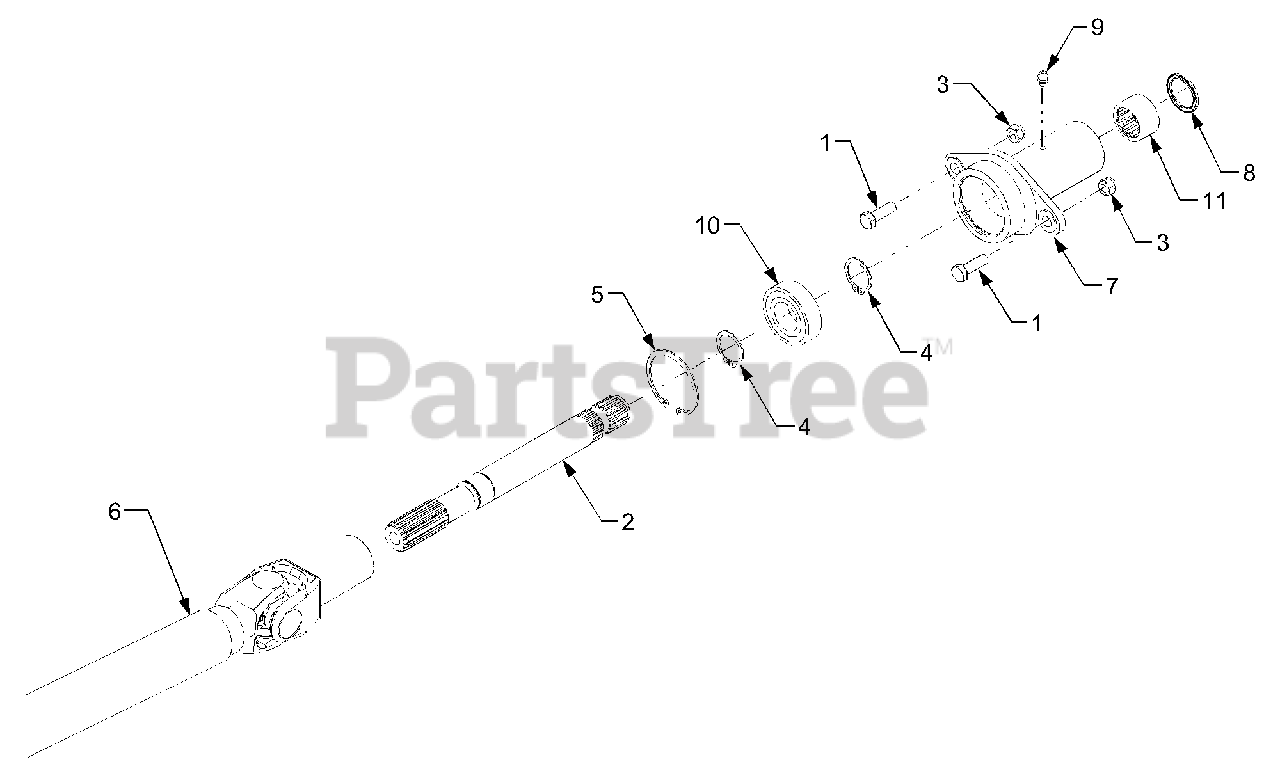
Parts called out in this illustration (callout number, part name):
1	Screw, Hex Cap, 5/16-18 x 1.0 GR5
2	Shaft, Splined, 1.0 Dia.
3	Nut, Hex Insert Lock, 5/16-18 GR5
4	Ring, Snap, 1.0 Dia. Shaft
5	Ring, Internal Retaining, 2.0 Dia
6	Shaft, Drive
7	Carrier, Shaft
8	Seal, Oil, 1.31 x 1.0
9	Fitting, Lube
10	Bearing, Ball
11	Bearing, Needle, 1.0 x 1.3125 x .75
